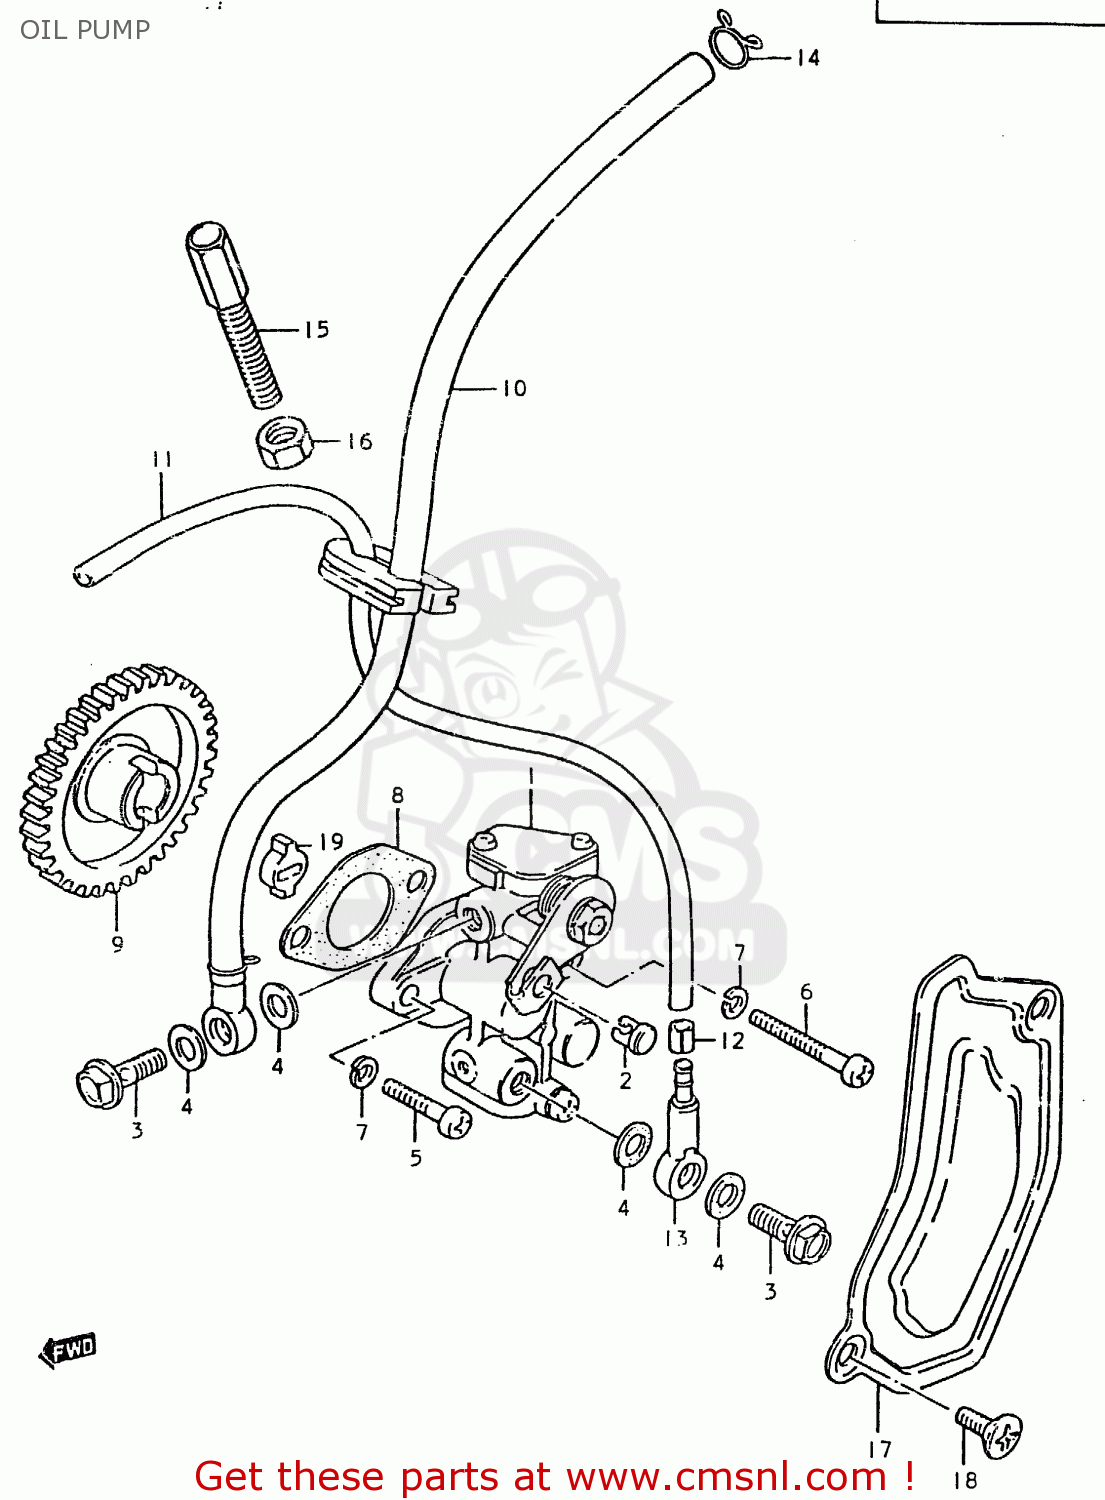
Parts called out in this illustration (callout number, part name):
1	PUMP ASSEMBLY,OIL
2	TERMINAL,CABLE
3	UNION BOLT
4	GASKET(6.2X11X1).2 (NAS)
5	SCREW
6	SCREW
7	LOCK WASHER
8	GASKET,OIL PUMP (NAS)
9	GEAR,OIL PUMP DRIVE
10	HOSE,INLET
11	HOSE,NO.2
12	CLIP
13	VALVE,CHECK
14	CLIP
15	BOLT
16	NUT
17	CAP,OIL PUMP INSPECTION
18	SCREW
19	PIECE,OIL PUMP DRIVE
